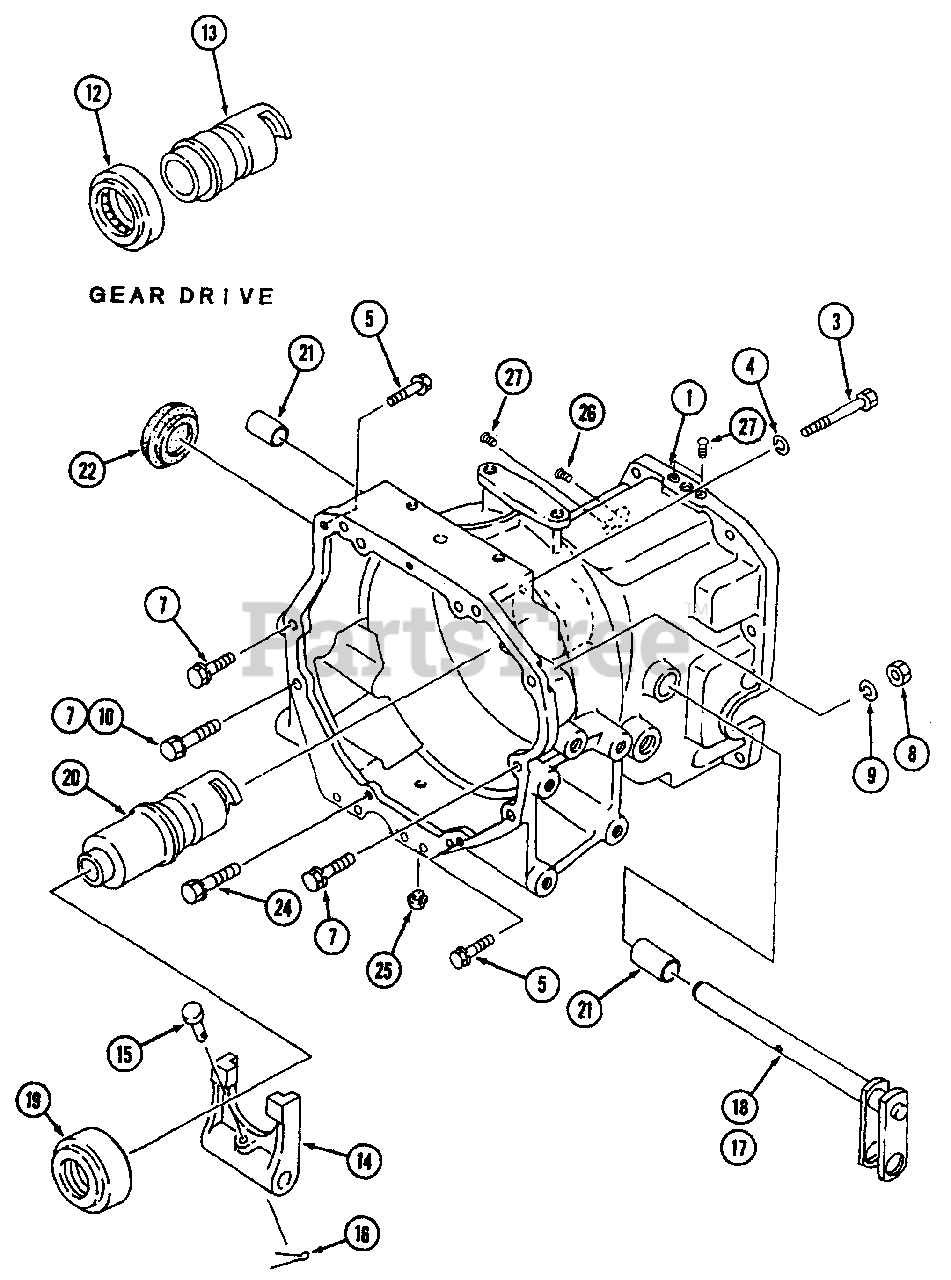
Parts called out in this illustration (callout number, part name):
1	Housing, Clutch
12	Bearing, Release
13	Hub, Release
14	Lever, Release
16	Pin, Split
17	Shaft, Release
18	Shaft, Release
24	Bolt
26	Plug
